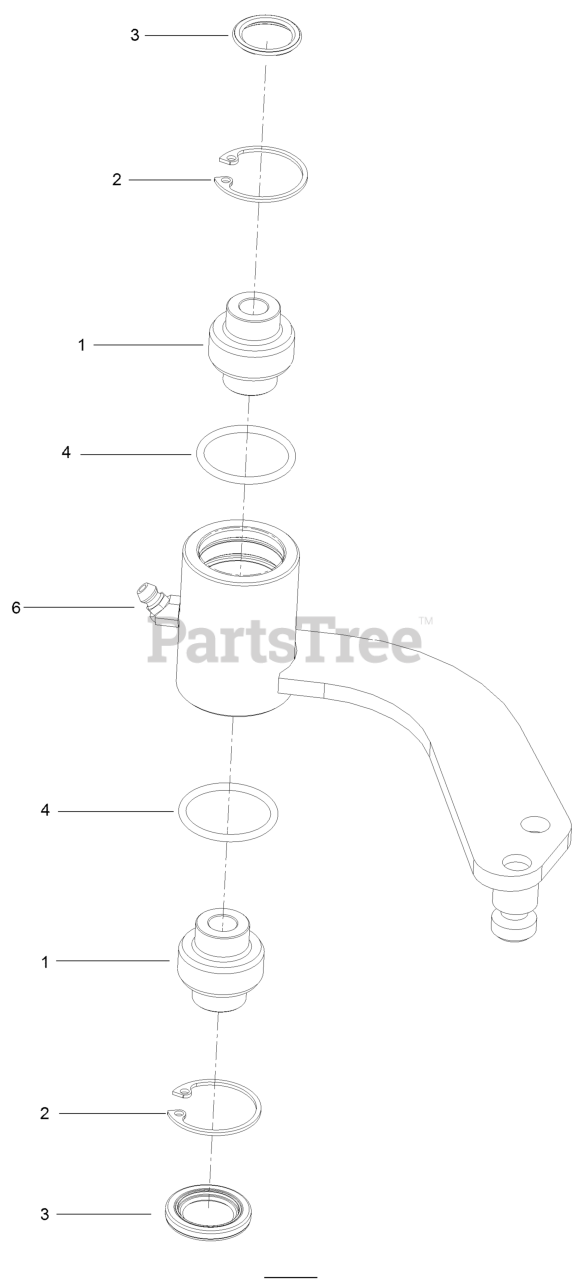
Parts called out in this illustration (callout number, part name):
1	BEARING-SPHERICAL
2	RING-SNAP
3	SEAL-LIP, SINGLE
6	FITTING-LUBE, 45 DEG
